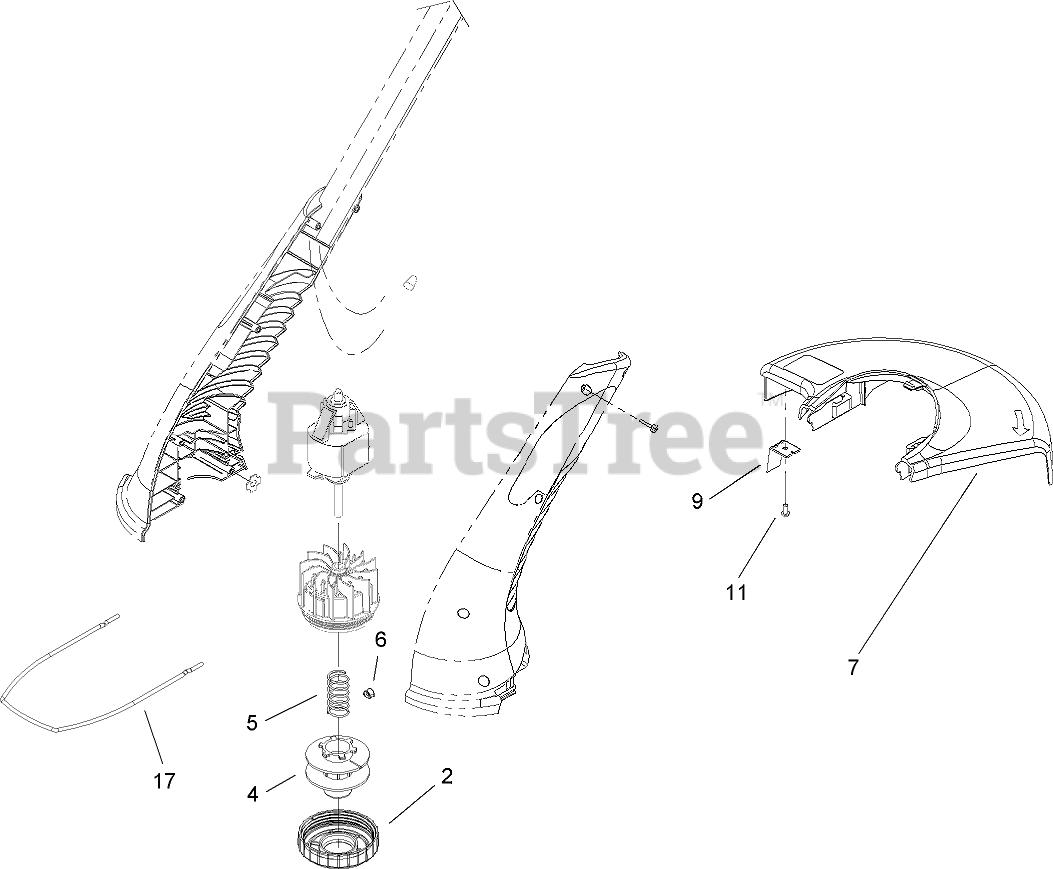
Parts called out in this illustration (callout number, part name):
2	Cap-Drum
4	.065 SPOOL ASM
5	Spring-Extension
6	EYELET-GUIDE
7	SHEILD-12 INCH
9	Blade-Cutoff
11	Screw-PPH
17	GUIDE-EDGE, 12 INCH
